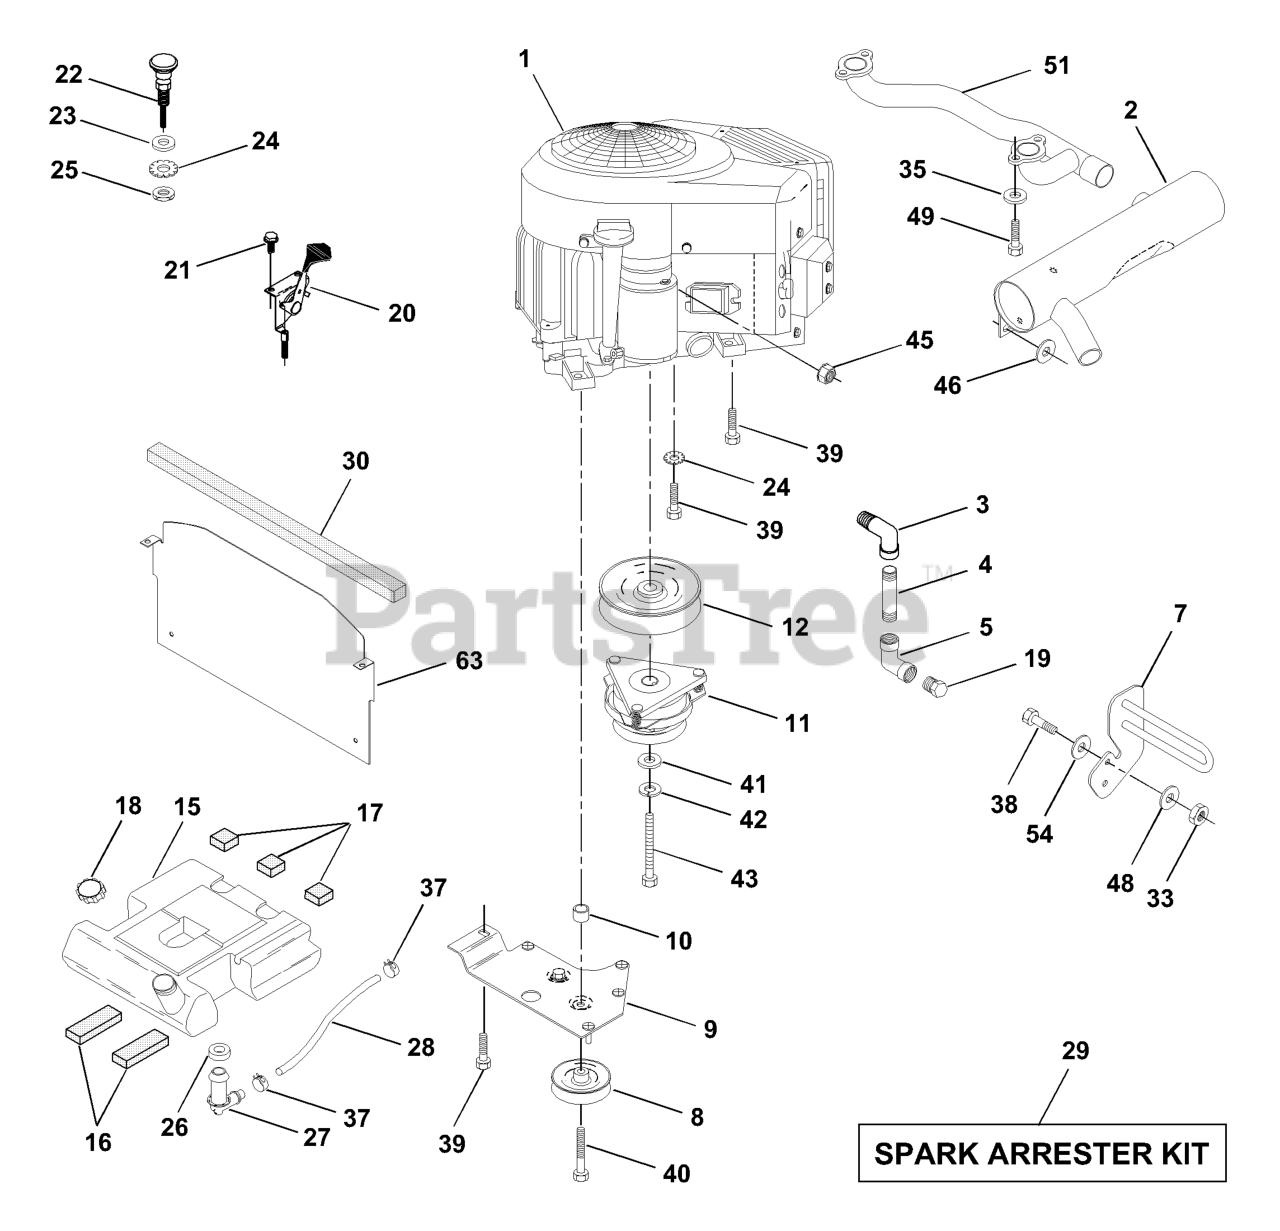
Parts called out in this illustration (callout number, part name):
2	MUFFLER VGT CYLINDER
3	STREET ELBOW LT NLA
4	Nipple Pipe 3/8NPT X 3 - 1/2
5	ELBOW
7	MUFFLER GUARD
8	RP.IDLER GROOVED
9	BELT KEEPER
11	CLUTCH.ELECT.CVX.105 FT/LB.
12	PULLEY, ENGINE
15	FUEL TANK
16	PAD IDLER TI
17	PAD-SPACER LT
18	FUEL CAP
19	PLUG T
20	THROTTLE CONTROL
21	SCREW LT
22	CHOKE CONTROL
23	WASHER
24	LOCKWASHER
25	NUT
26	BUSHING OUTLET T
27	STEM FUEL TANK
28	HOSE
29	SPARK ARRESTOR
30	FOAM-STRIP LT
33	NUT
35	WASHER.LOCK.HVY.HLCL.SPR.5/16
37	HOSE CLAMP
38	BOLT
39	SCREW LT
40	Screw Thdrol 3/8 - 16 X 3 - 1/4
42	LOCKWASHER
43	BOLT
45	NUT
46	WASHER
48	Washer 13/32 x 1-1/4 x 7 Ga.
51	EXHAUST PIPE
63	SHIELD.HEAT.VGT.
